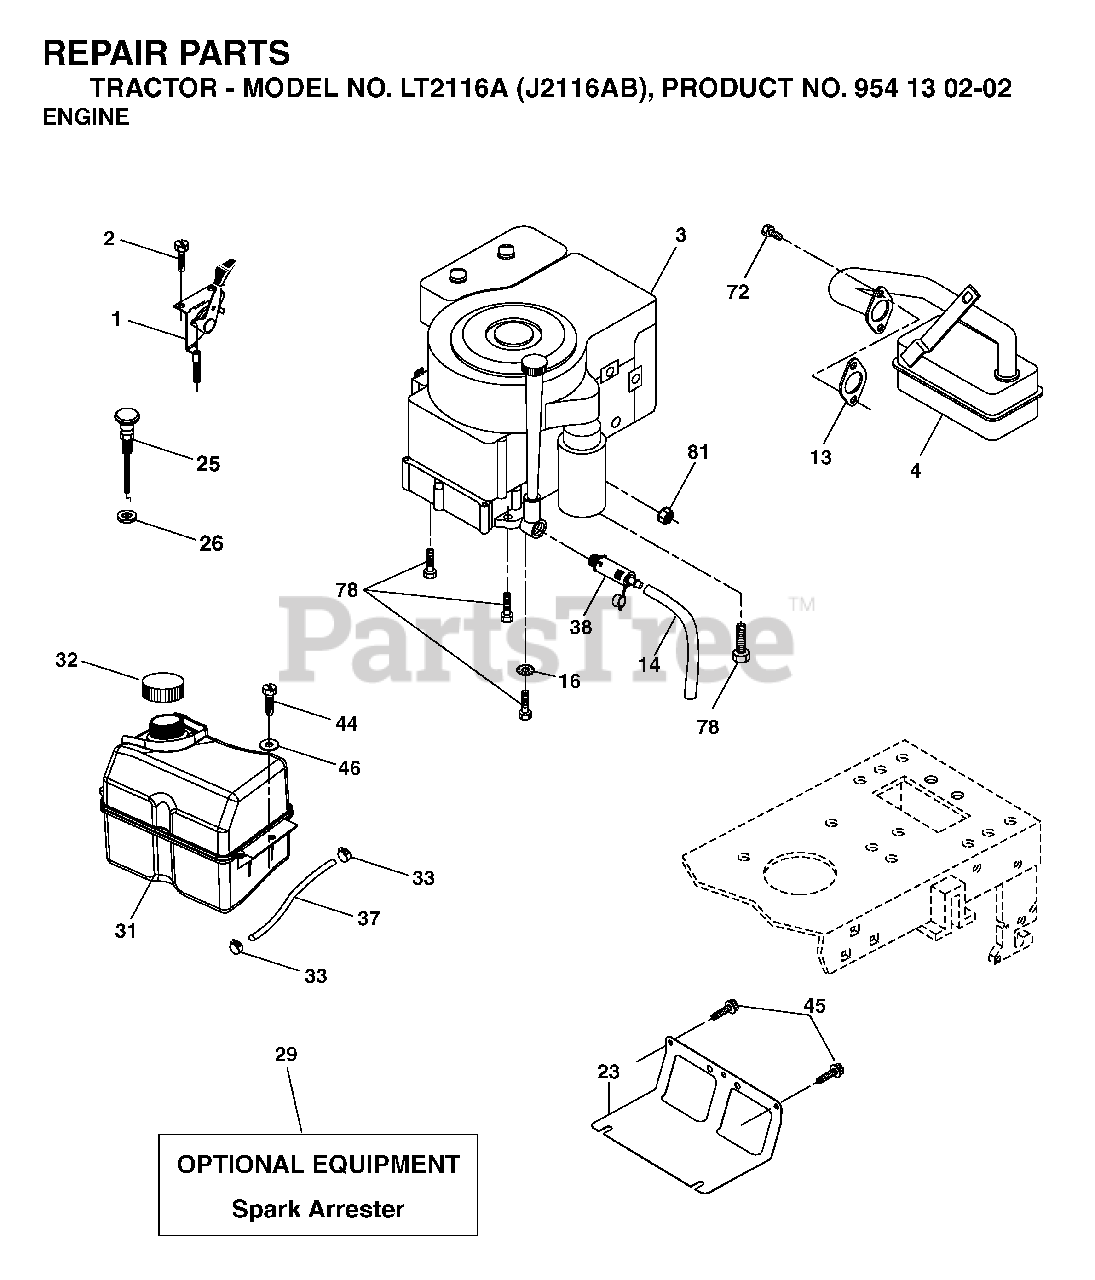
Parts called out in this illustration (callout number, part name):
1	CONTROL TH/CH FLAG
2	SCREW
13	REPL BY 532 27 22-93
14	TUBE, DRAIN OIL ASM.
16	LOCKWASHER
23	SHEILD.BROWNING.DBR.GUARD
26	NUT KEPS 3/8 - 24 UNF
29	ARRESTER SPARK (OPTIONAL)
31	TANK FUEL
32	FUEL CAP
33	HOSE CLAMP
37	LINE.FUEL.20
38	PLUG DRAIN OIL EASY
44	SCREW HEXWSHR 1/4-20X3/4
45	SCREW, 3/8-16X3/4
72	SCREW.SOCKET.HEAD.5/16-18
78	SCREW.3/8-16
81	NUT
